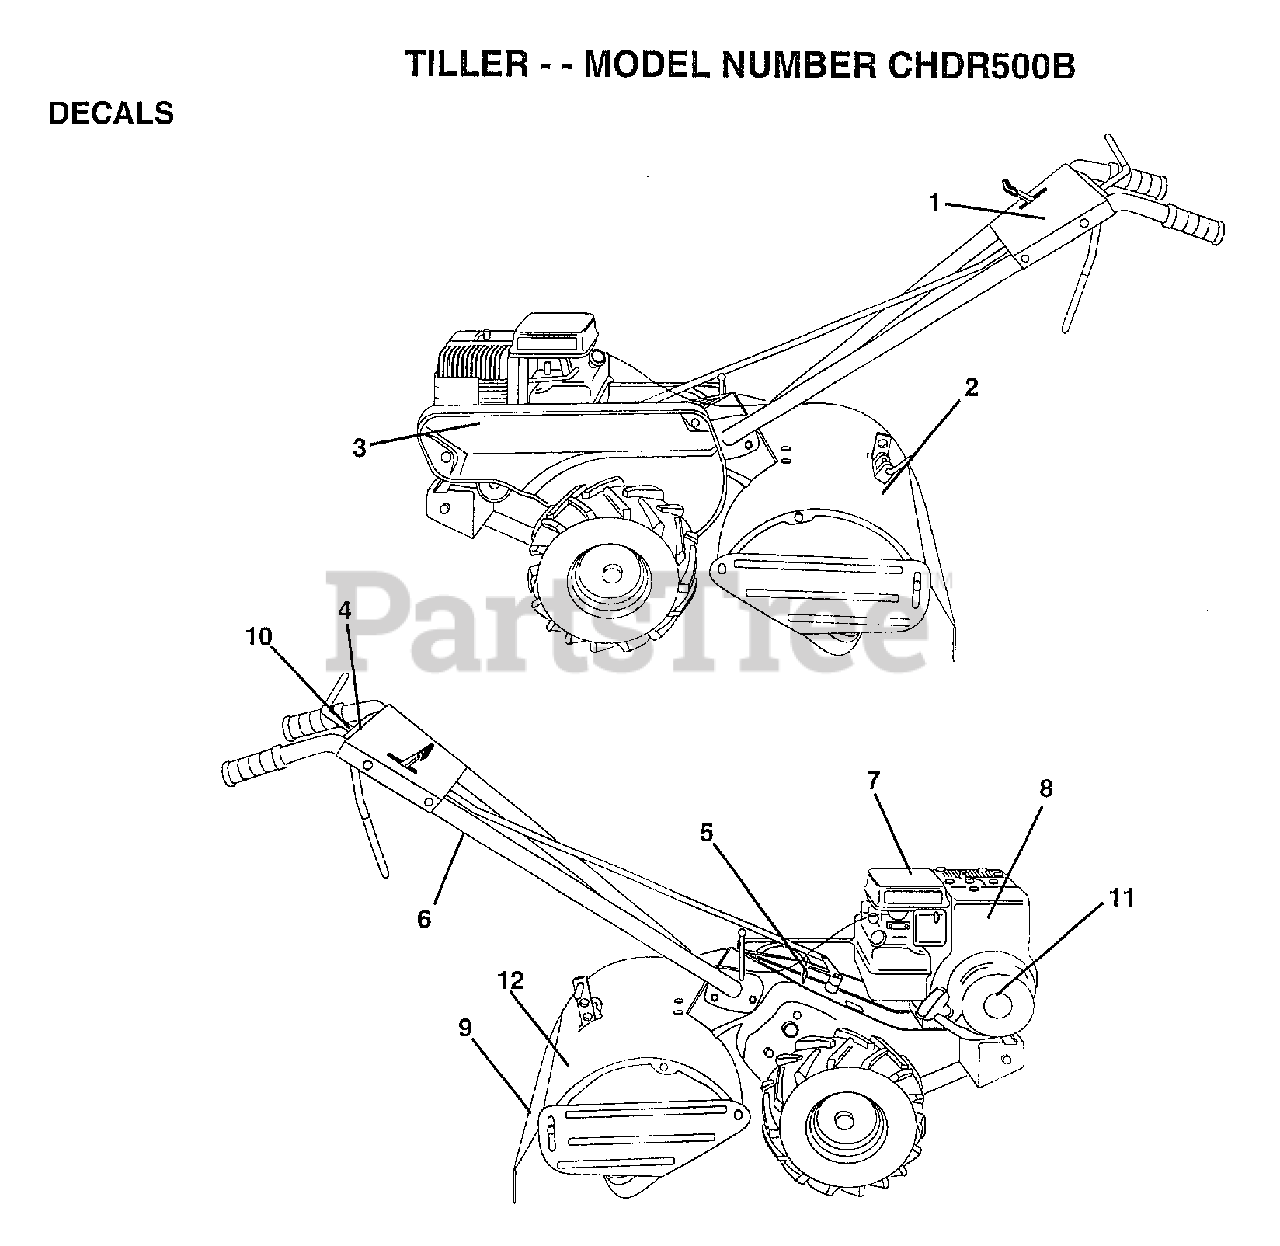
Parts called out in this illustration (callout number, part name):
1	"DECAL PANEL,CTRL"
2	"DECAL SHIELD,TINE"
3	"DECAL GUARD, BELT"
5	DECAL CRT
6	DECAL TI
7	DECAL TI
8	DECAL, BRIGGS & STRATTON
10	DECAL REVERSE
12	DECAL.CAUTION
